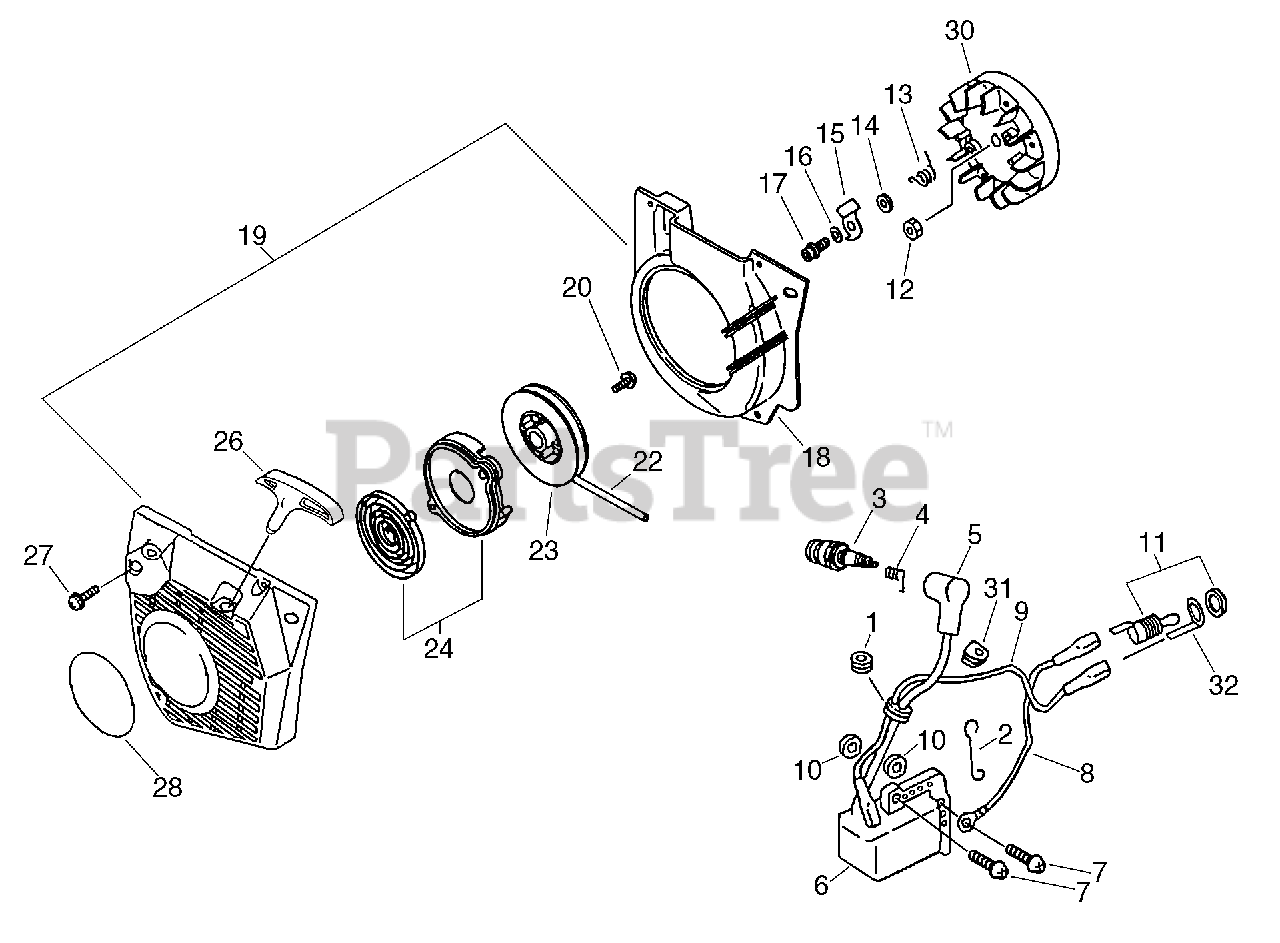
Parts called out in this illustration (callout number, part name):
3	SPARK PLUG - BPMR7A
4	TERMINAL, SPARK PLUG
5	CAP, SPARK PLUG
6	COIL, IGNITION
7	SCREW 5×25
9	LEAD - GROUND
10	WASHER 5.2×12×3
11	SWITCH, ON-OFF
12	NUT, FLANGE M8
13	SPRING, TORSION
14	SPACER 5.2×8×2.1
15	PAWL, STARTER
16	WASHER 5.5×12×0.8
17	SCREW 5×12
18	COVER, FAN
19	CASE, STARTER
20	SCREW
22	ROPE, STARTER
23	REEL, ROPE
24	SPRING, RECOIL
26	GRIP, STARTER
27	SCREW 4×16
28	LABEL, ECHO
30	FLYWHEEL
32	TERMINAL, GROUND
